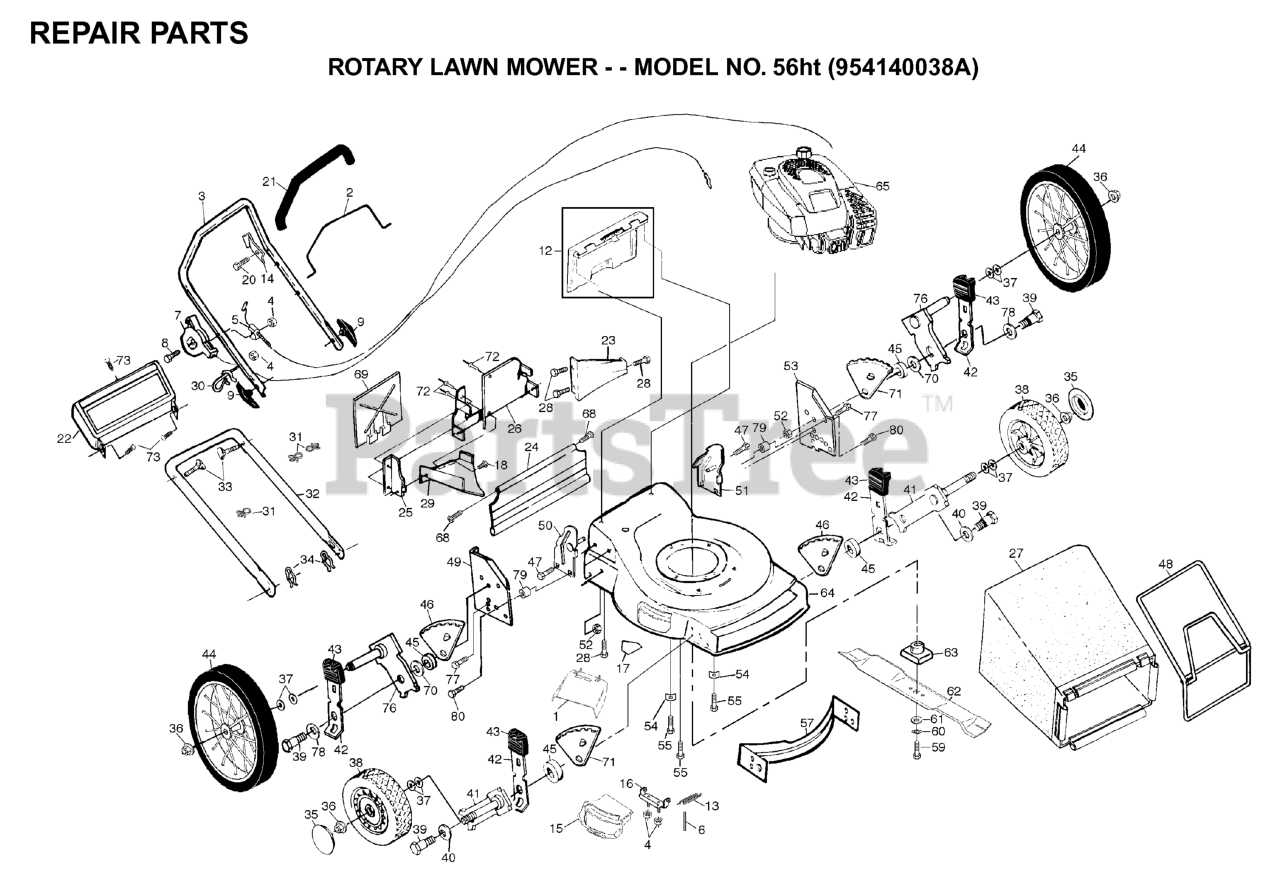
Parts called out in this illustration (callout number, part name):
2	CONTROL BAR/BLACK
3	UPPER HANDLE
4	NUT
5	CABLE ASSEMBLY
6	ROD.HINGE.COMBI-C
7	THROTTLE CONTROL
8	SCREW 1/4-20 X 2.12
9	HANDLE KNOB
13	SPRING HINGE
14	BRACKET UPSTOP
16	BRACKET.HINGE ASM.W/FIN
17	DECAL HYT
18	SCREW.HXTAP.10-24
20	TAPPING SCREW
21	HANDLE GRIP
22	TRIM PLATE
23	REAR BAFFLE
24	REAR SKIRT
25	SIDE BAFFLE
27	GRASS BAG
29	DISCHARGE BAFFLE
30	ROPE GUIDE
31	CLIP CABLE SNAP
32	HANDLE, LOWER
33	HANDLE BOLT
34	HAIRPIN COTTER
35	HUBCAP.8".GREY
36	HEX FLANGE LOCKNT
37	WAVE WASHER
38	WHEEL.8X2.PR.LP.RAD.GREY
39	BOLT
40	WASHER.BELLEVILLE (3 2 LB)
41	AXLE ARM
42	SELECTOR SPRING
43	SELECTOR KNOB
44	WHEEL TIRE PM
45	RP SPACER HT ADJ
46	WHL ADJ BRKT LF/RR
47	SELF-TAPPING SCREW 5/16-18X3/4
48	CATCHER.FRAME.WALK
50	HANDLE BRACKET ASSEMBLY-RIGHT
51	HANDLE BRACKET ASSEMBLY - LEFT
52	LOCKNUT PM
54	WASHER.ENGINE.BZP
55	BOLT 3/8-16X1-1/8
57	FRONT BAFFLE
59	SCREW, HEX HD 3/8-24 X 1-3/8
60	LOCKWASHER
61	WASHER,HARDEN
63	BLADE ADAPTOR
68	HINGE SCREW
69	MULCHER PLATE
70	WASHER.FLAT.1/2
71	WHL ADJ BRKT RF/LR
72	RIVET BLIND
